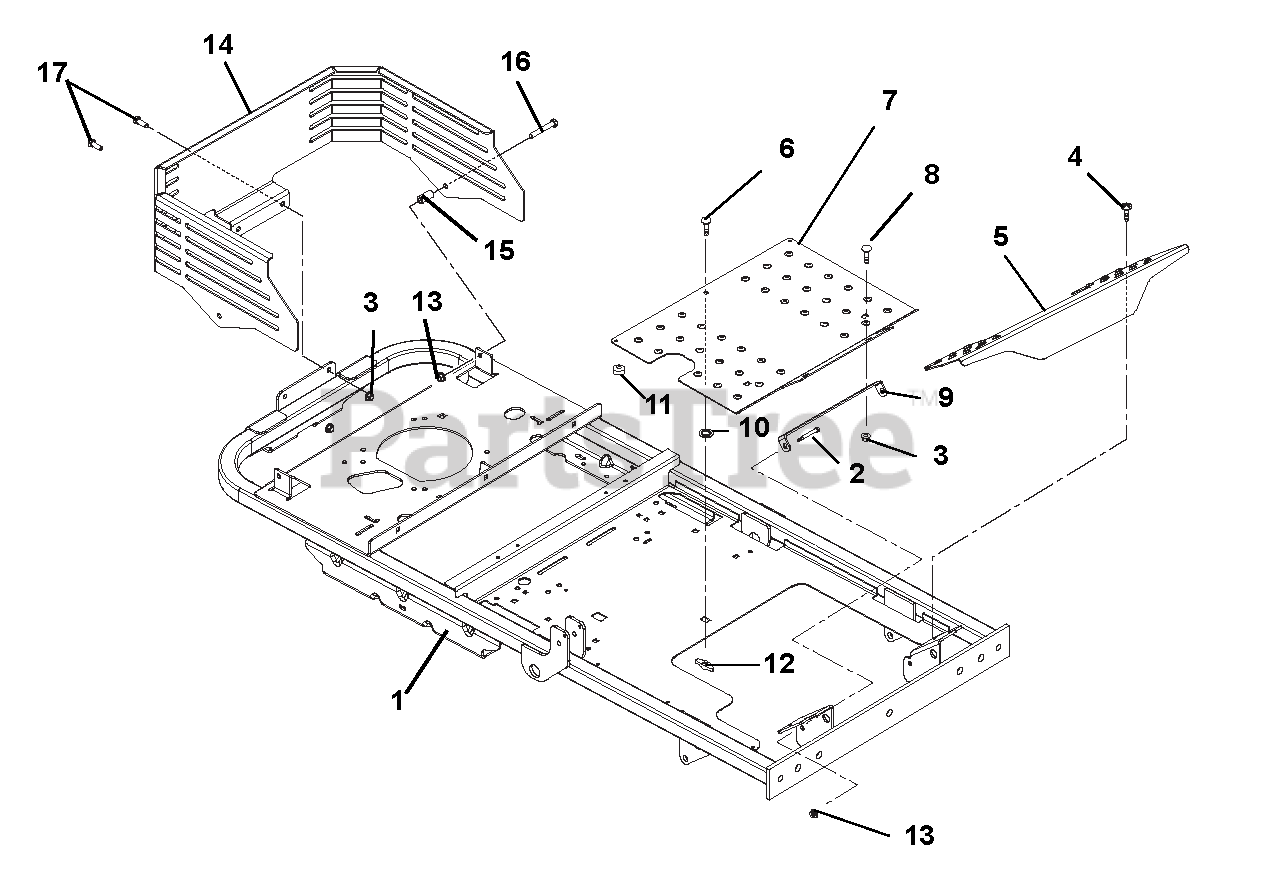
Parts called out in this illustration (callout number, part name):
1	WMT, PIVOTING AXLE FRAME
2	BOLT-SHLDR .375-16X.150
3	@NUT-LK-NYL-FLG .38-16 YWZC
4	@SCR-TAP .31-18X.50 HWH TR YWZ
5	FOOTREST
6	@BLT-RDHDSQNK .31-18X1.00 G5YZ
7	PAINTED FOOTREST ASSEMBLY
8	@BLT-RDHDSQNK .38-16X1.00 G5YZ
9	BRACKET, DECK ACCESS
10	NUT-PUSH .312
11	BUMPER GROMMET
12	KNOB - WING .312-18 UNC
13	@NUT-LK-TOP-FLG .38-16 YWZC
14	ENGINE GAURD, PAINTED W/DECALS
15	BSHG, SPCR .390X.625X1.25 PM
16	@BLT-HEX .38-16X2.50 GR5 YWZC
17	@BLT-HEX .38-16X1.00 GR5 YWZC
